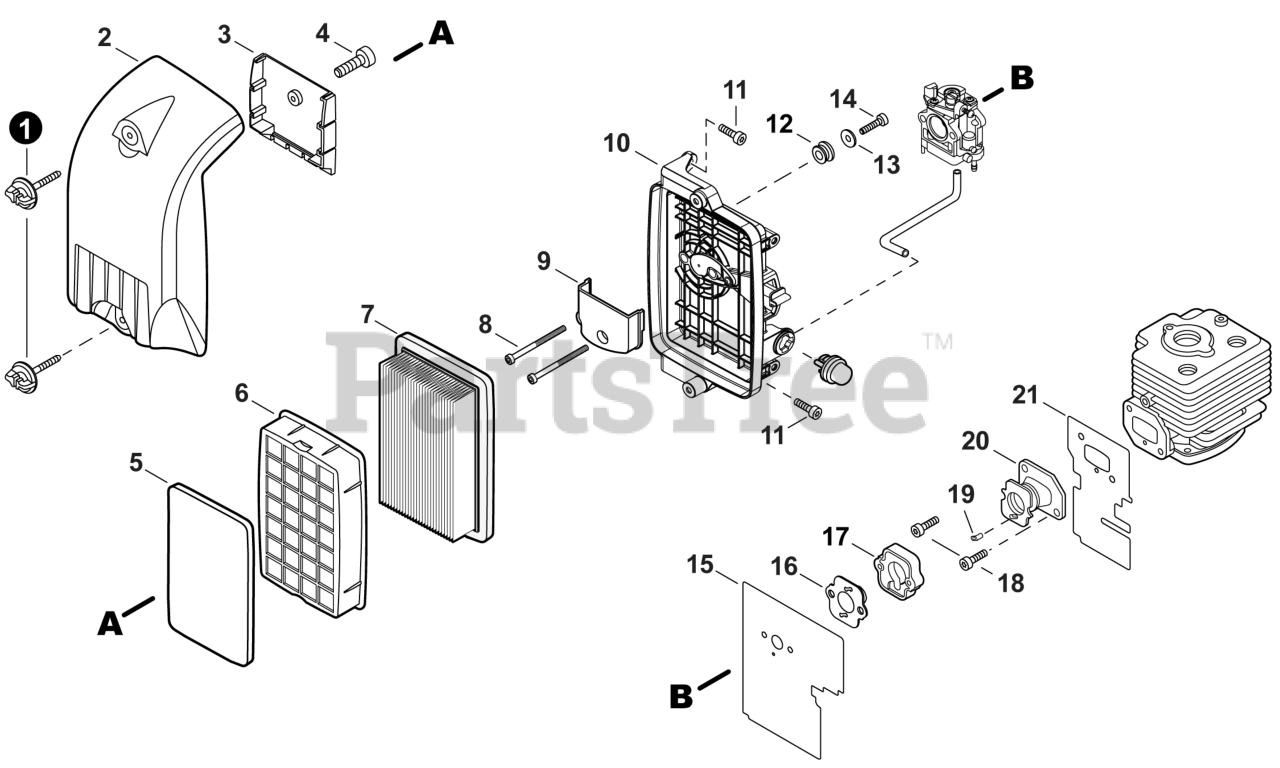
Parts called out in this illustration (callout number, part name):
1	THUMBSCREW
2	COVER, AIR FILTER
3	SUPPORT, PRE-FILTER
4	BOLT, TORX 4x12
5	PRE-FILTER, FOAM
6	RETAINER, PRE-FILTER
7	FILTER, AIR
8	BOLT, TORX 5x55
9	PLATE, PREVENT
10	CASE, AIR FILTER
11	BOLT, TORX 5x20
12	GUIDE, CABLE
13	WASHER 5.5x16x0.8
14	BOLT, TORX 5x16
15	HEAT SHIELD, INTAKE
16	GASKET, INTAKE
17	ADAPTOR, INTAKE
18	SCREW 5x12
19	COLLAR 3
20	BELLOWS, INTAKE
21	HEAT SHIELD, INTAKE
